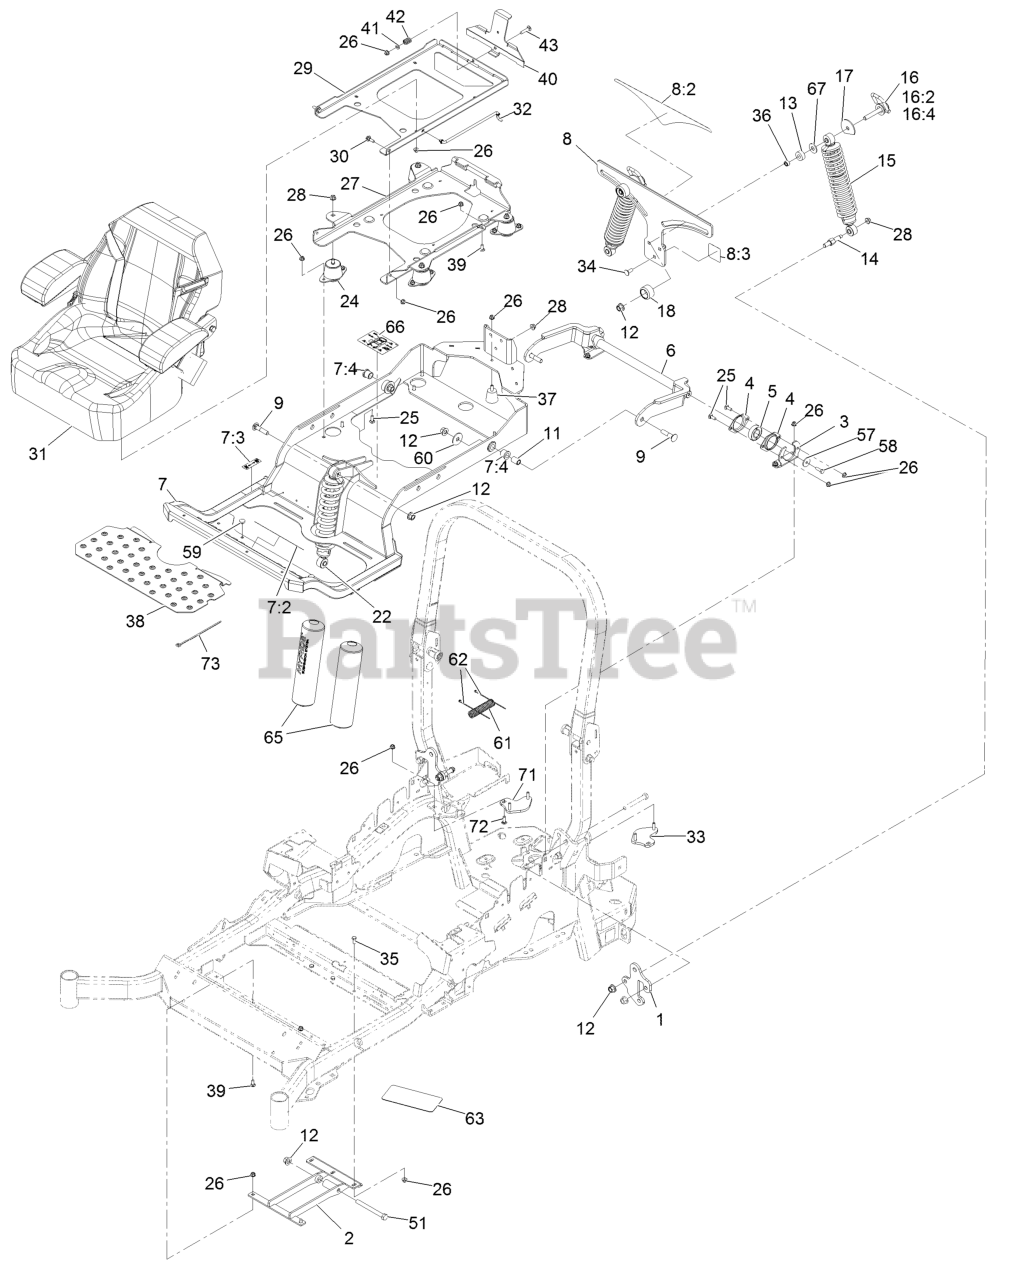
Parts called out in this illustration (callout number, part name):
1	PLATE-MOUNT, SHOCK
2	MOUNT-LOWER
3	BRACKET-BEARING
4	HOUSING-BEARING, FLANGE
5	BEARING
6	ARM-TRAILING
7	SUBFRAME ASM
7:2	DECAL-DANGER
7:3	DECAL-BRAKE, PARKING
7:4	BUSHING-FLANGE
8	BRACKET-MOUNTING
8:2	DECAL-ADJUSTMENT, RIDE
8:3	DECAL-LOCK, CAM
9	SCREW-CARR
11	SPACER-ALUMINUM
12	Nut-Lock 1/2-13
14	BOLT-SHOULDER
16	CAM LOCK ASM
16:2	CAP-LOCK
16:4	NUT-HEX
17	PLATE-STOP
18	KNOB-FRONT
24	ISOLATOR-SEAT
25	BOLT-CARR
26	NUT-HF, NI
27	PLATE-SUPPORT, ISO SEAT
28	NUT-HF, NI
29	PLATE-FRAME, SEAT
30	SCREW-SHOULDER
31	SEAT-EXMARK STANDARD
32	ROD-PROP
33	LH PLATE ASM (W/STUDS)
34	SCREW-CARR
35	SCREW-HH
36	BEARING-NEEDLE
37	BUMPER-RUBBER
39	SCREW-CARR
40	PLATE-LATCH,SEAT
41	WASHER-PLAIN
42	SPRING-COMPRESSION
43	BOLT-CARR
51	SCREW-HH
57	WASHER-FLAT
58	SCREW-HH, THREAD LOCKING
60	WASHER-THRUST
61	COVER-HOSE
62	TIE-CABLE
63	TREAD-GRIP
65	COVER-SHOCK
66	DECAL-SERVICE AID
67	WASHER-FLAT
71	RH PLATE ASM (W/STUDS)
72	SCREW-CARR
73	TIE-PLASTIC
